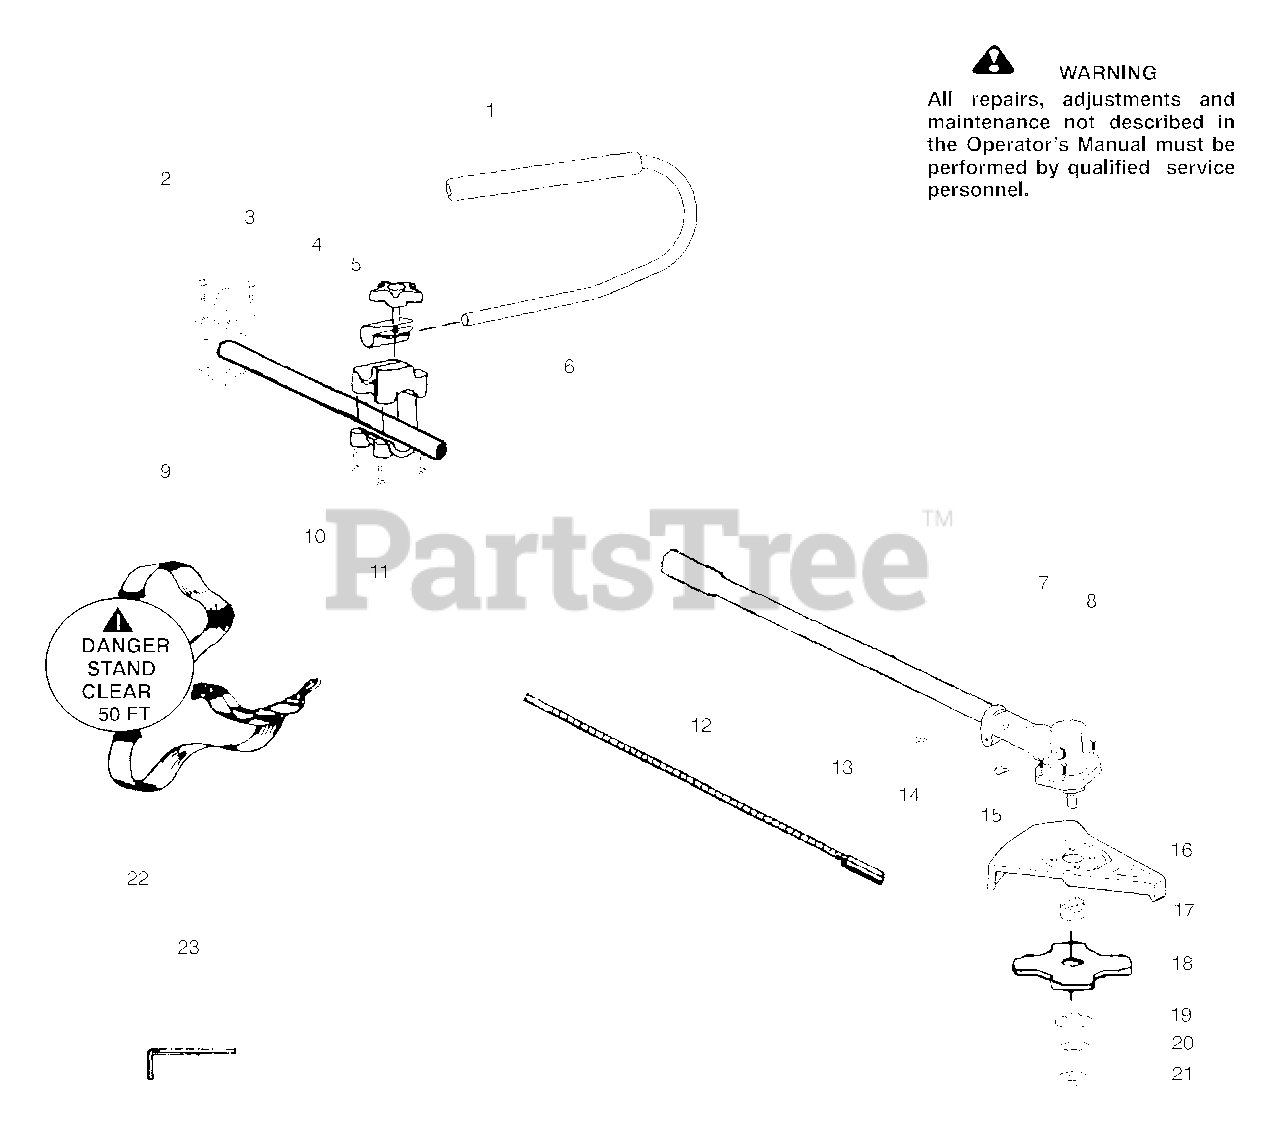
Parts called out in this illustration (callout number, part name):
1	Kit-Handlebar Assy.
2	Clamp-Harness Upper
4	Clamp-Handlebar
5	Knob
6	Base-Clamp
7	Assy-Gearbox
9	Clamp-Harness Lower
10	Kit-Clamp-Tube
12	Flexshaft-Split boom
13	Assy.-Driveshaft
16	Kit-Blade Shield
17	Dust cup - Blade
18	Accy.-Weed Blade (8")
19	Washer-Blade Retaining
20	Washer-Belleville
21	Nut-Flange
22	Assy-Shoulder Strap
23	Wrench-Hex (5/32")
